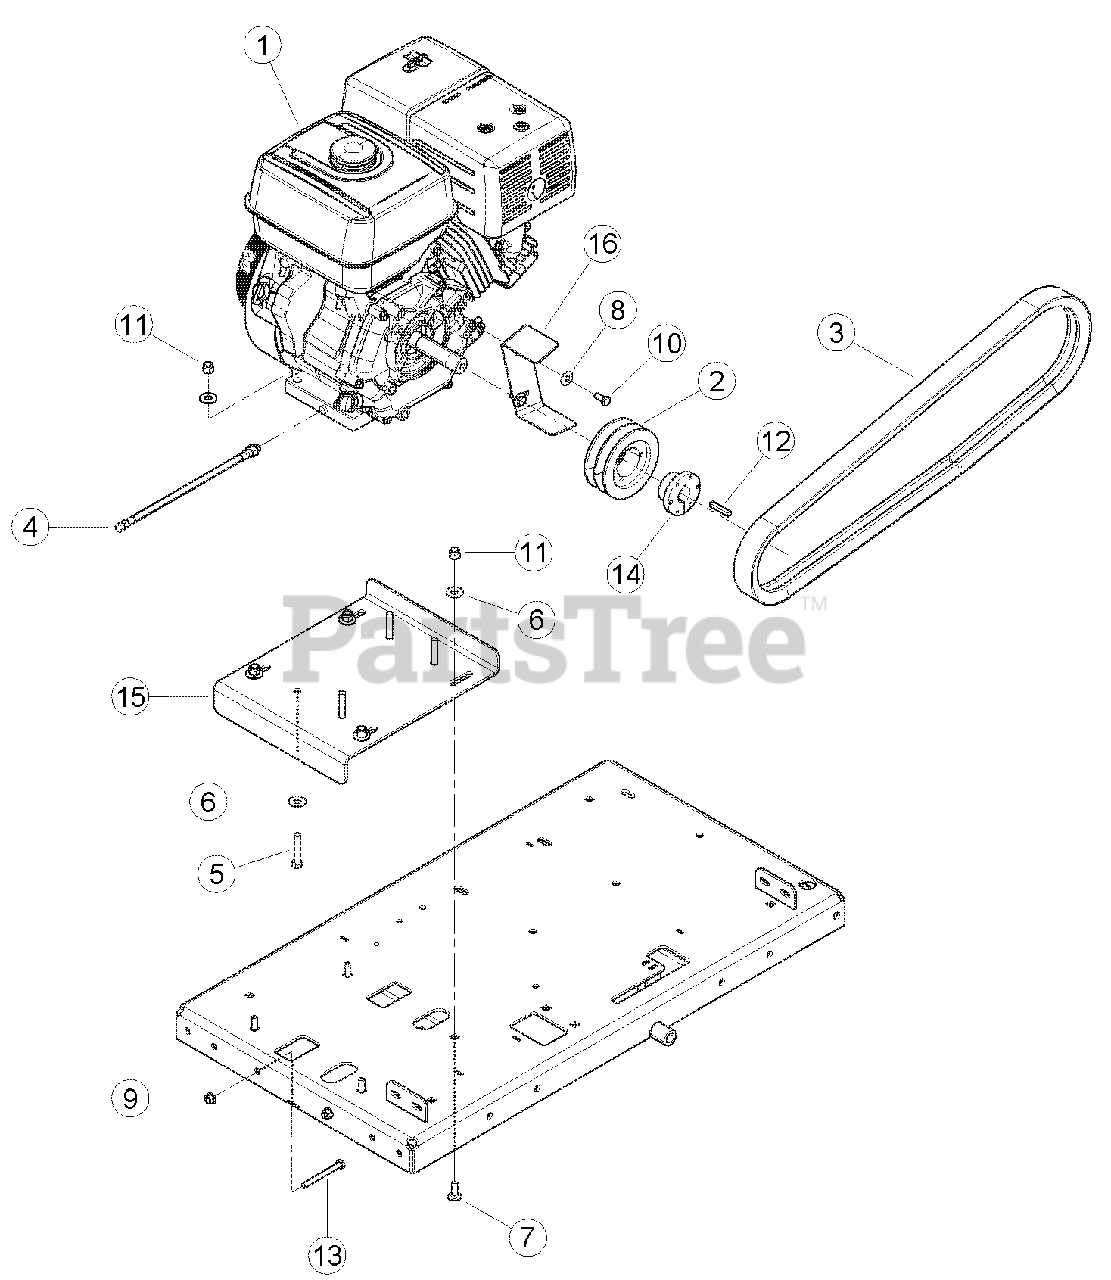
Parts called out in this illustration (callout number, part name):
1	ENGINE, 13 HP HONDA (FOR SERVICE SEE ENGINE OWNER'S MANUAL OR YOUR NEAREST AUTHORIZED HONDA ENGINE DEALER)
2	SHEAVE, 2B4.4 SH, QD
3	BELT, 2RB61 ARAMID
4	HOSE ASSY, CRANKCASE DRAIN
5	BOLT, 3/8 X 2 HEX HD GR5 ZP
6	WASHER, 3/8 FLAT ZP
7	BOLT, 3/8 X 1 CRG GR5 NC ZP
8	WASHER, 5/16 FLAT ZP
9	NUT, 5/16 SERR FLANGE NC ZP
10	BOLT, 5/16-24 X 3/4 HEX HD GR5 ZP
11	NUT, 3/8 NE NYLOCK ZP
12	KEY, 1/4 SQUARE X 1-1/2 LONG PLAIN
13	BOLT, 5/16 NC X 3 FULL THD
14	BUSHING, SH 1"
15	PLATE, 13 HP HONDA ENGINE
16	GUIDE, BELT
17	PLATE, 13 HP HONDA ENGINE
18	GUIDE, BELT
